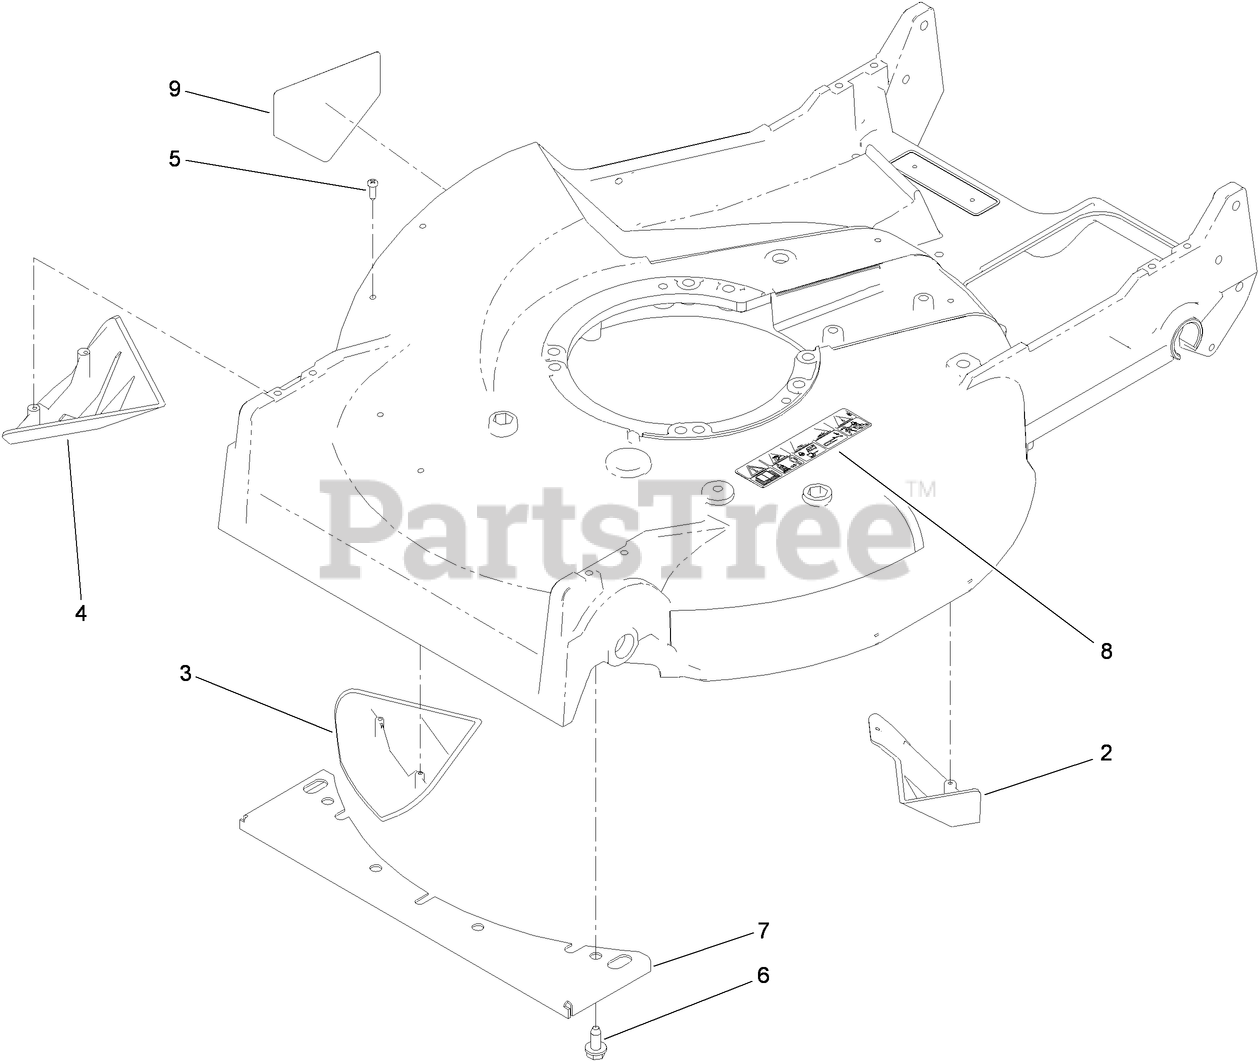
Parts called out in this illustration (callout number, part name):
2	KICKER-REAR
3	KICKER-FRONT
4	KICKER-RH
5	SCREW-PPH
6	SCREW-HWHTF
8	DECAL-DANGER
9	DECAL-DANGER
